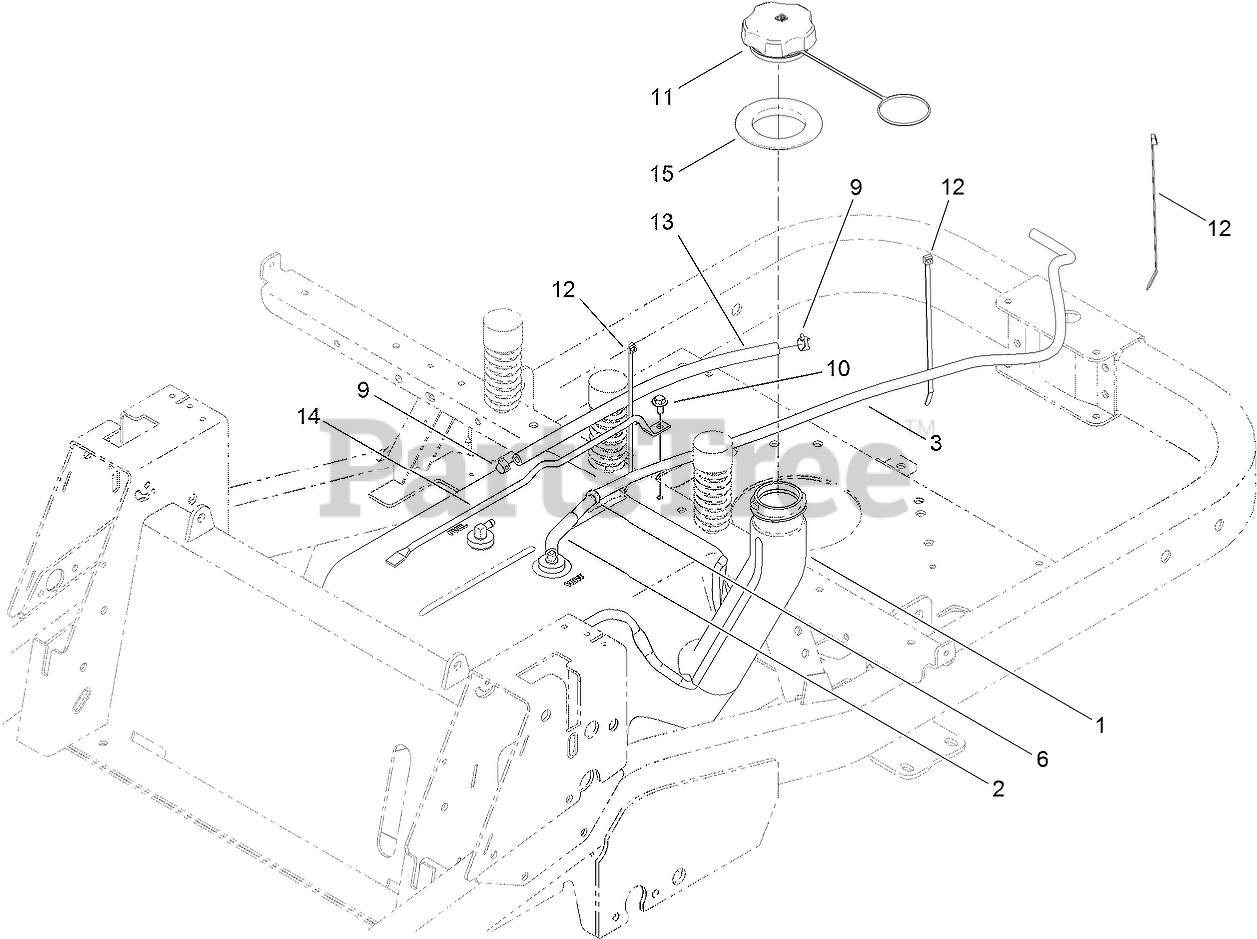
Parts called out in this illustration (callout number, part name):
1	FUEL TANK ASM
2	HOSE-FUEL
3	HOSE-FUEL
6	ADAPTER-ORIFICE
9	CLAMP-HOSE
10	SCREW-HHFTF
11	CAP-FUEL, RACHETING
12	TIE-CABLE
13	HOSE-FUEL
14	ROD-TANK, GAS
15	SEAL-TANK
